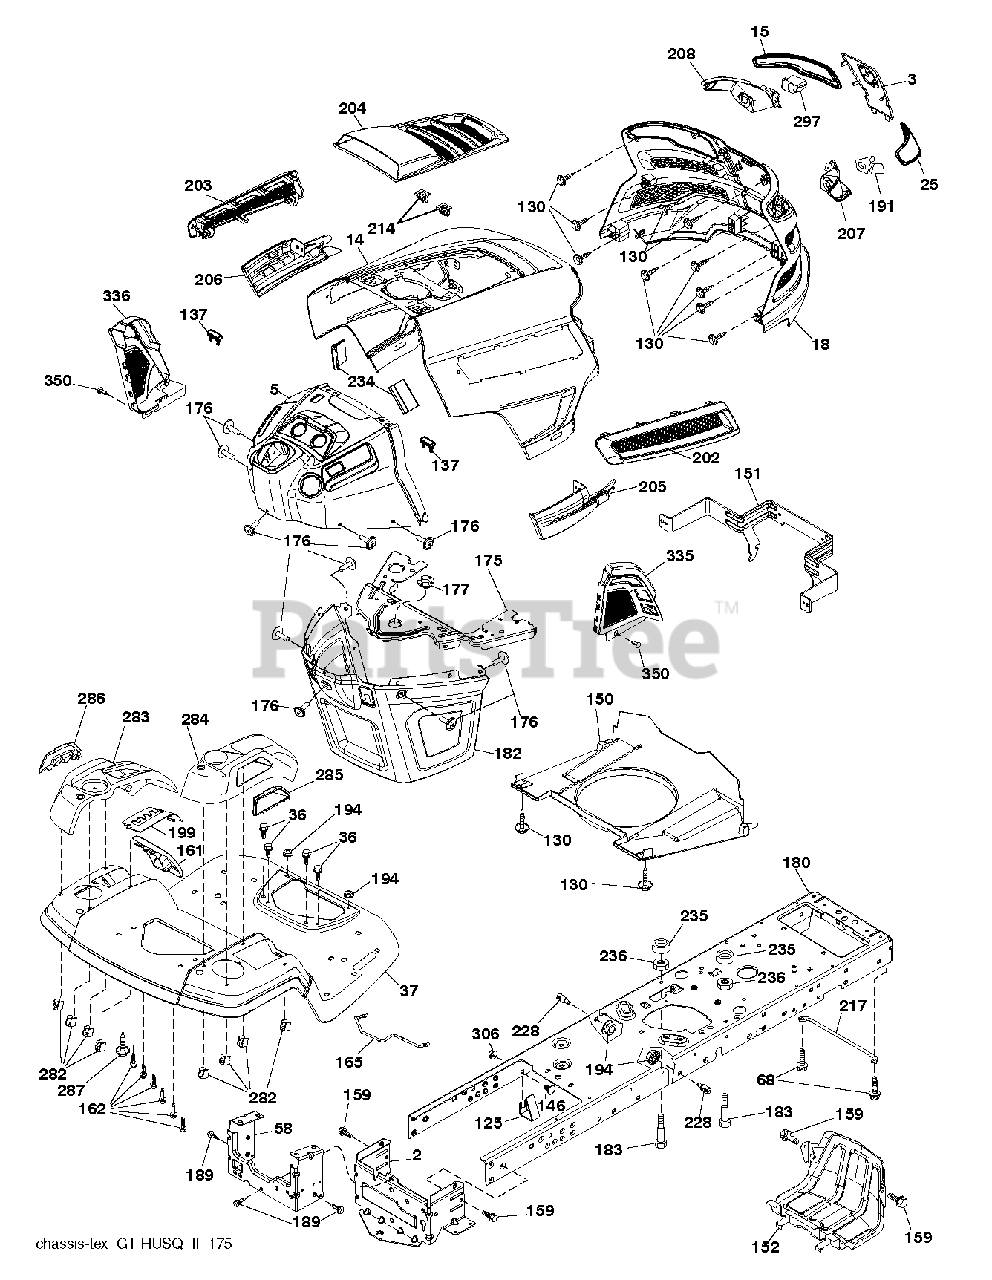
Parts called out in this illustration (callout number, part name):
2	DRAWBAR.LOWER.2PC.18/22
3	APPLIQUE.SUBASM.GT.HUSQ.II
5	DASH.UPP.GT2.DUAL.RD.PTO.MCHOK
14	HOOD.ASM.HUSQVARNA.GT.TEX.422
15	LENS.HEADLIGHT.LH.GTII.2011
18	GRILLE.SUBSTRATE.2011.
25	LENS.HEADLIGHT.RH.GTII.2011
36	SCREW 5/16"
37	FENDER.TLT.FS.W/CPH/FW/RSF.668
58	DRAWBAR UPPER 2PC SMALL FENDER
68	SCREW LT
125	CLIP.FUEL.LINE
130	SCREW.#10 X 0.750.BOS
137	BUMPER DASH
146	BOLT.RDHD.SHT.SQNK.3/8-16X5/8
150	AIR.DUCT.GTV.BLACK
151	BRACKET.PIVOT.HOOD.GT.HUSQ.II
152	SHIELD.BROWNING.PNT.GT.V2
159	SCREW, 3/8-16X3/4
161	WINDOW.FUEL.LT.HUSQ.TEX.498
162	SCREW.HI-LO.CONSOLE
165	SUPPORT.TANK.REAR.B/TE
175	PLATE.CROSSMEMBER.HUSQ
176	SCREW.#10-24X5/8.RN.QU
177	BUSHING STEERING
180	CHASSIS.TEX.BOLTED
182	DASH.LOWER.COMMON.12V.ADAPTOR
183	BOLT.5/16-18X1-1/4 FULL THD
189	SCREW
191	INSERT.REFLECTIVE.RH.HUSQ.GTII
194	NUT LOCK HEX FLANGE 5/16-18
199	PLATE.DECK.LIFT.HUSQ.LT
202	VENT.SIDE.RH.GT.HUSQ.II.
203	VENT.SIDE.LH.GT.HUSQ.II.498
204	VENT.TOP.HUSQ.GT2
205	SIDE.TRIM.RH.GT.HUSQ.II
206	SIDE.TRIM.LH.GT.HUSQ.II.GRAY
207	BEZEL LIGHT.RH.GT.II.MYLAR
208	BEZEL LIGHT.LH.GT.II.MYLAR
214	CLIP.RETAINER.TINNER.
217	ROD.PIVOT.HOOD
228	STUD.FASTNER.W/ANTI-ROTATE
234	BUMPER.HOOD.TEX.HUSQVARNA
235	SPACER FENDER
236	NUT.CENTERLOCK.5/16-
282	CLIP.RETAINER.CONSOLE.LT.HUSQ
283	CONSOLE.ASM.LFT.RSF.HUSQ.LT
284	CONCOLE.CNTRL.PDL.HUSQ.LT.498
285	CONSOLE INSERT RH
286	CONSOLE.INSRT.LH.HUSQ.LT.BLACK
287	SCREW 1/4X20
297	INSERT.REFLECTIVE.LH.HUSQ.GTII
306	NUT LOCK FLG 3/8-16 UNC
335	COVER.LOWER.DASH.RH.BLACK
336	COVER-LH.LOWER.DASH.GT2.BLACK
350	CLIP.X-MAS.TREE
